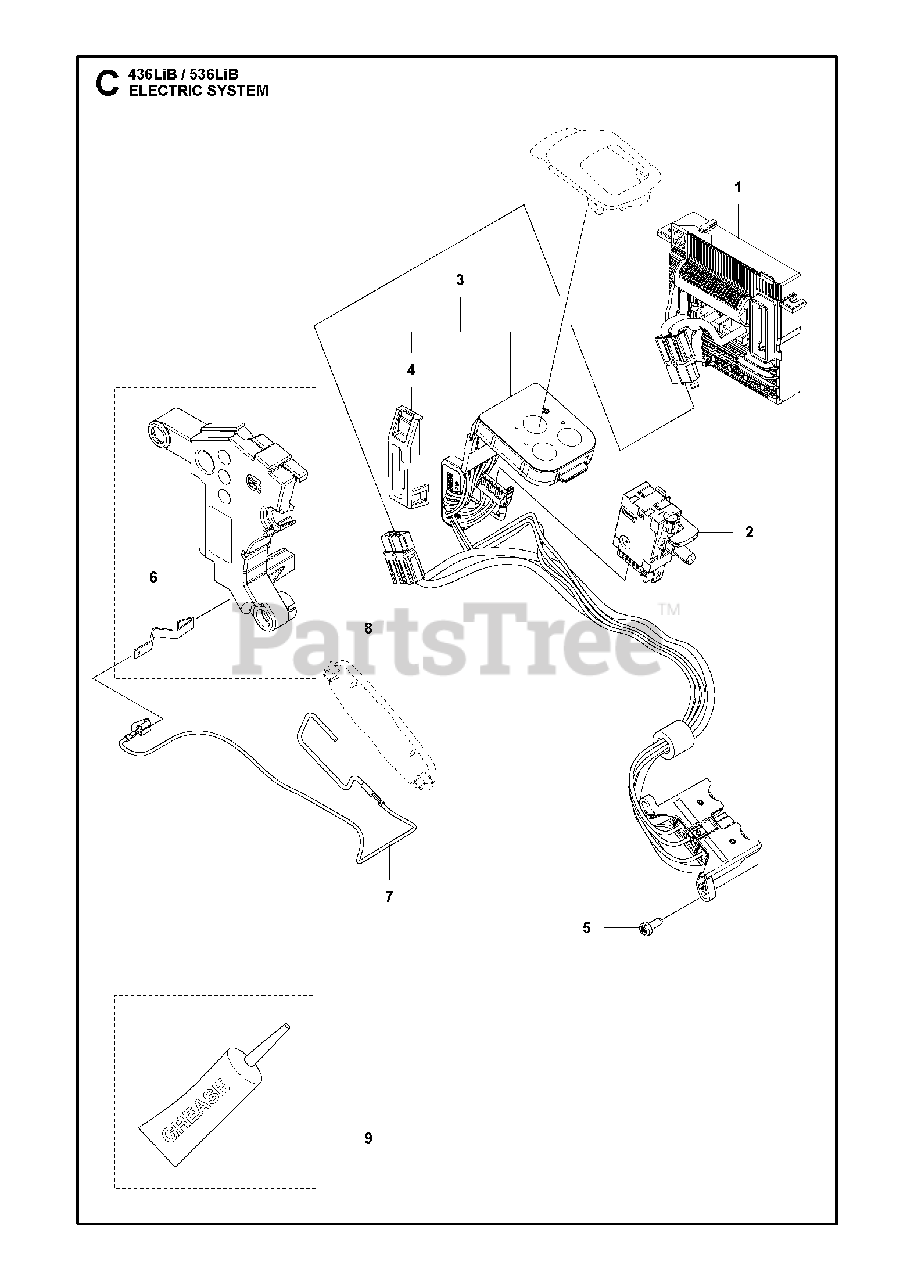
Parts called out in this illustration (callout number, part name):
1	CONTROL UNIT BLDC MID SPEC, GE
2	TRIGGER SWITCH
3	WIRING ASSY BLOWER MAIN
4	BRACKET
6	SPRING
7	WIRING ASSY
8	KIT COVER ELECTRONICS
9	GREASE TUBE Q8 RUYSDAEL WR2
